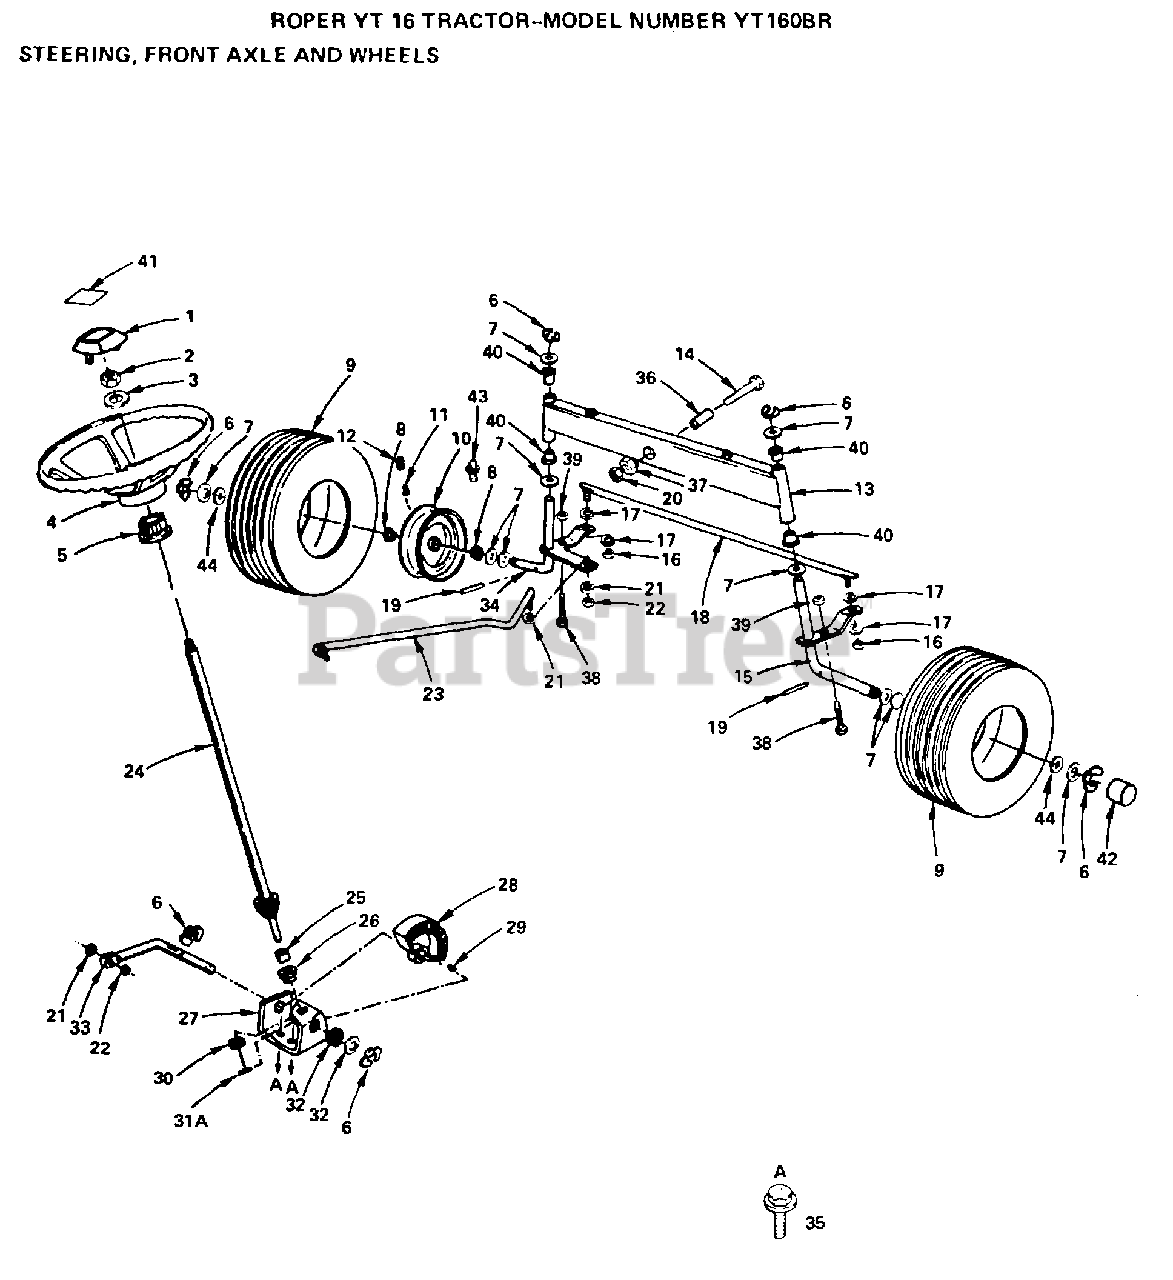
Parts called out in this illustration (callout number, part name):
1	INSERT-WHEEL LT
2	NUT
3	WASHER
5	ADAPTER LT
6	RING
8	"FLANGE, BEARING"
11	VALVE STEM LT
12	VALVE CAP
13	AXLE ASSY YTV
16	NUT
17	LOCKWASHER
20	LOCKNUT M
21	LOCKWASHER
23	DRAG LINK LTV
25	SHAFT SPACER LT
26	BUSHING
28	GEAR-SECTOR T
30	WASHER D
32	WASHER .T
33	ROD STEERING LT
34	SPINDLE LH LTV
35	SCREW
38	BOLT
39	NUT
40	COL. SRTG. BEAR.
41	DECAL - STEERING WHEEL
42	HUB CAP
43	FITTING LT
44	WASHER LT
